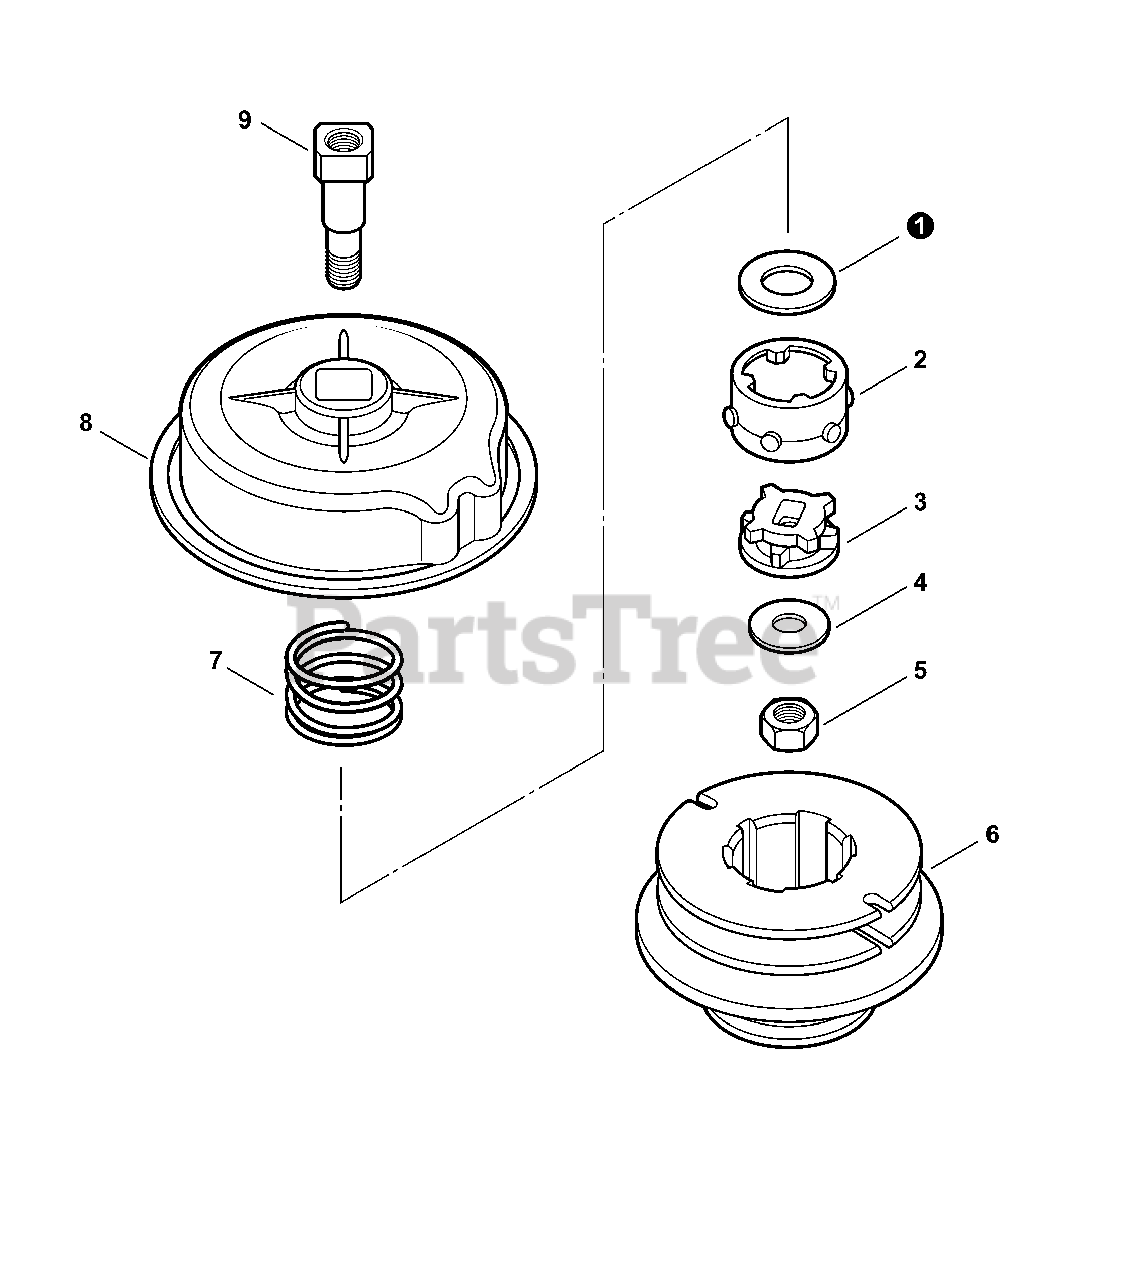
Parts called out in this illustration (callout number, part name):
1	WASHER, FLAT
2	CAM, OUTER
3	CAM, INNER
4	WASHER, FLAT
5	NUT, LOCK
8	HOUSING
9	BOLT, SHAFT 10 MM
